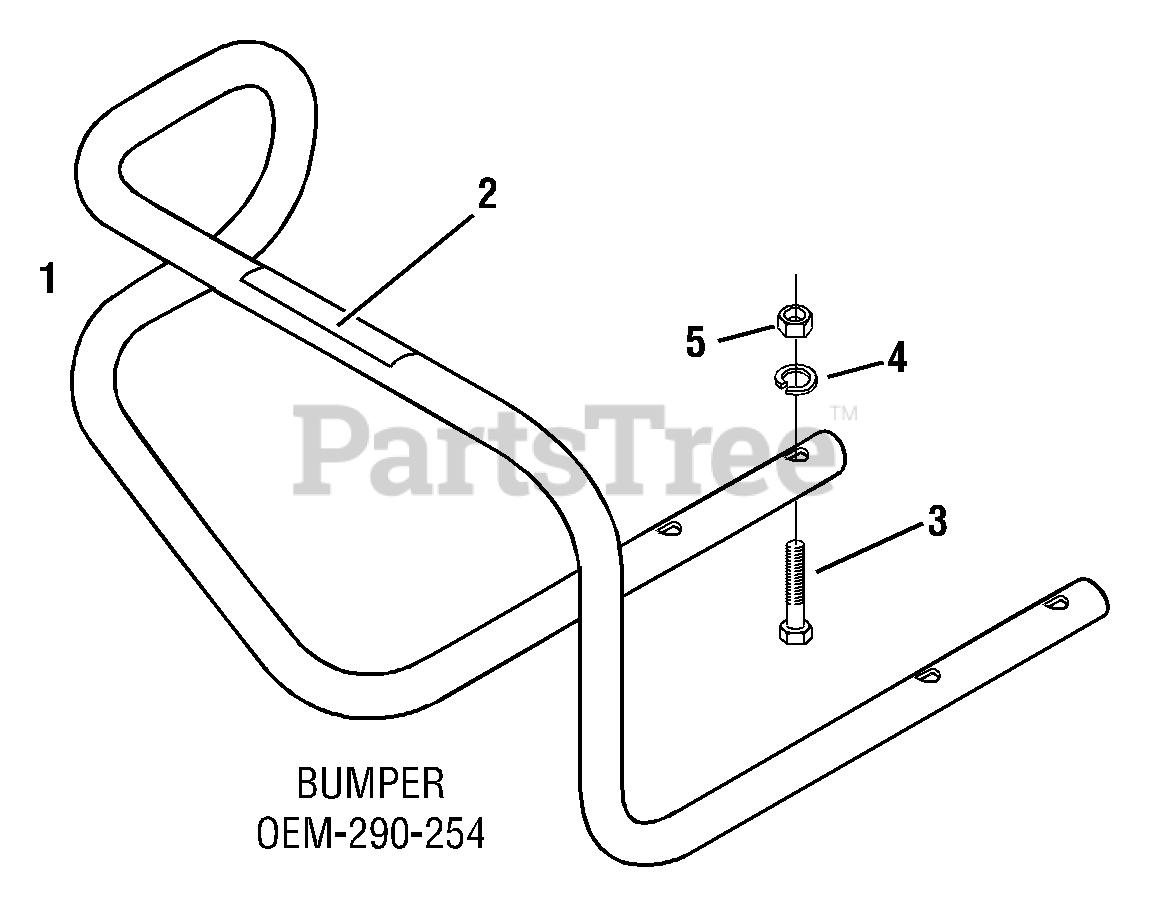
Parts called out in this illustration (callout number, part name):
2	Decal - Caution
3	Screw-hex hd., 5/16-18 x 2-1/4
4	Lockwasher-5/16
5	Lock Nut-Hex, Nylon, 5/16-18
